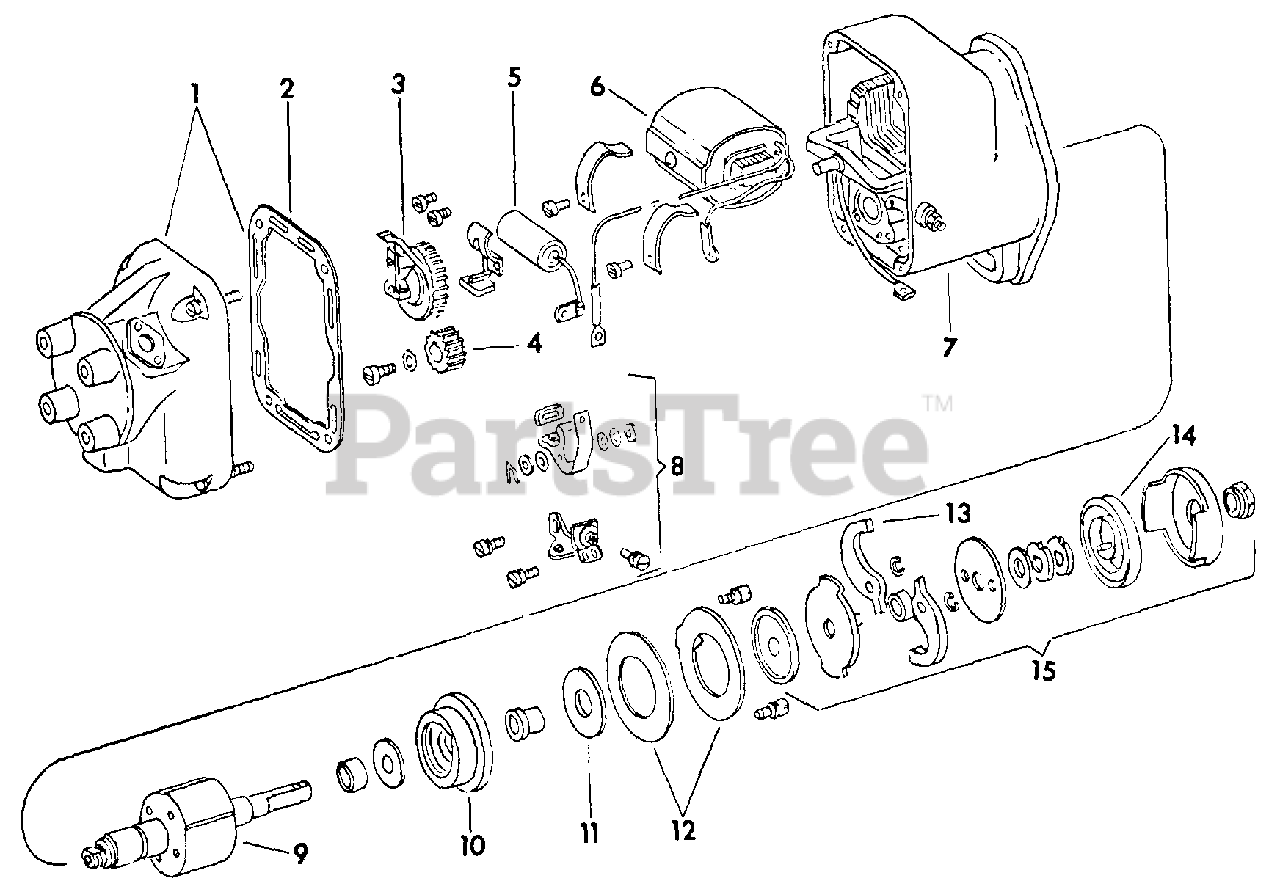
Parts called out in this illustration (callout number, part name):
1	CAP, DISTRIBUTOR
2	GASKET, DISTRIBUTOR CAP
3	ARM ASSEMBLY, DISTRIBUTOR
7	HOUSING, ASSEMBLY
8	SET, BREAKER POINT
10	CAGE ASSEMBLY, BEARING
12	STOP ASSEMBLY, IMPULSE
14	SPRING, DRIVE
15	COUPLING ASSEMBLY, IMPULSE
